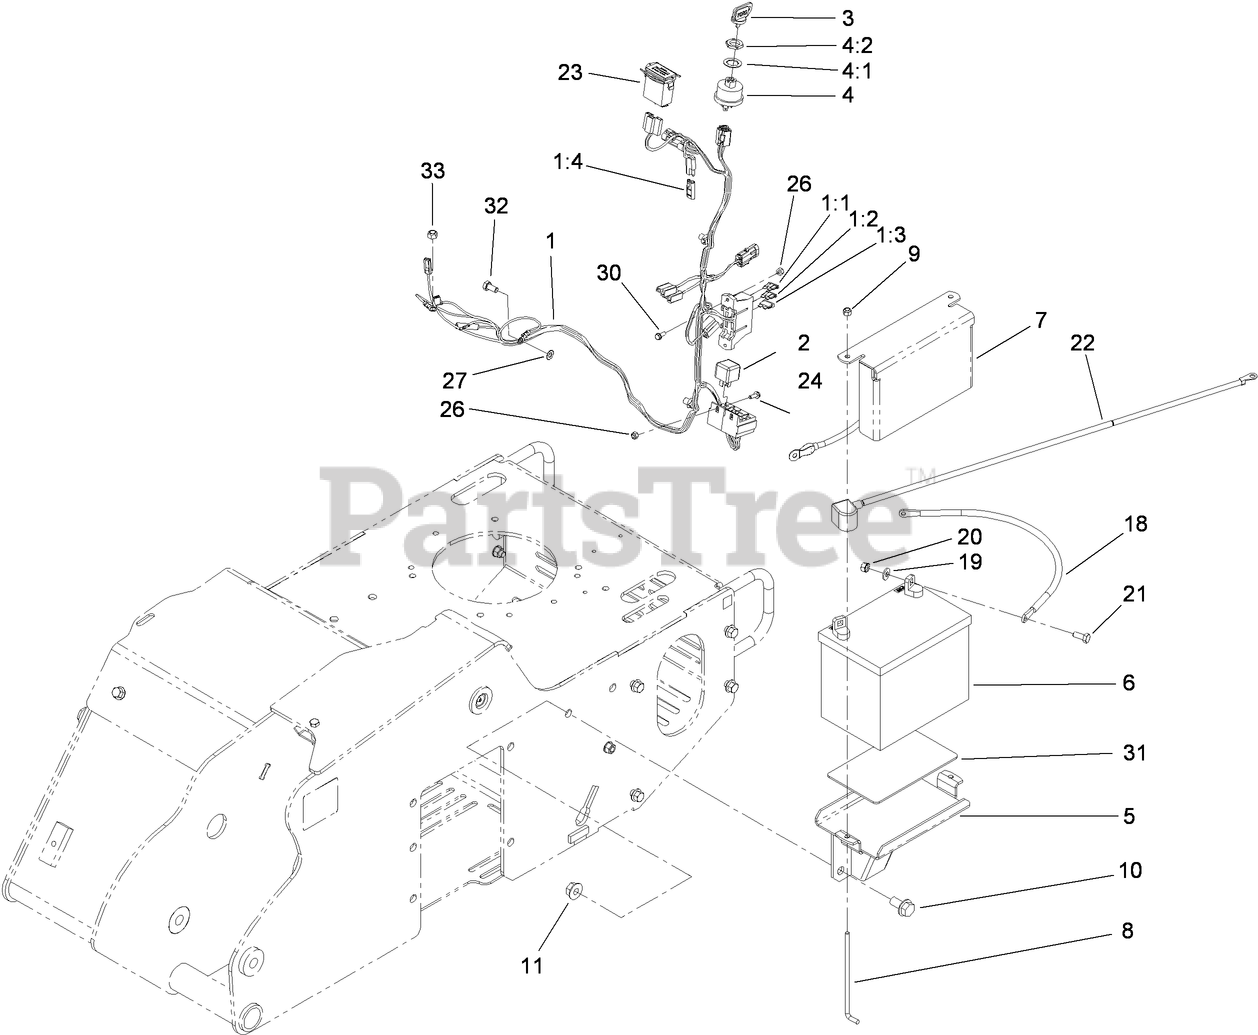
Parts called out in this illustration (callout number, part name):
1	HARNESS-WIRE
1:1	FUSE-BLADE, 30 AMP
1:2	FUSE-BLADE, 25 AMP
1:3	FUSE-BLADE, 20 AMP
1:4	CAP-PLUG
2	RELAY
3	KEY-IGNITION
4	Key Switch ASM
4:1	WASHER-TOOTH, INTERNAL
4:2	NUT-HH
5	TRAY-BATTERY
6	BATTERY-DRY
7	PLATE-HOLD DOWN, BATTERY
8	HOLDOWN-BATTERY
9	NUT-LOCK, NI
10	SCREW-HHF
11	NUT-HHF
18	CABLE-BATTERY, POSITIVE
19	WASHER-FLAT
20	NUT-KEPS
21	SCREW-HH
22	CABLE-BATTERY, BLACK
23	METER-HOUR
26	NUT-LOCK, NI
27	WASHER-LOCK
30	SCREW-HWH
31	PAD-SKID, ANTI
32	SCREW-HH
33	NUT-HF
